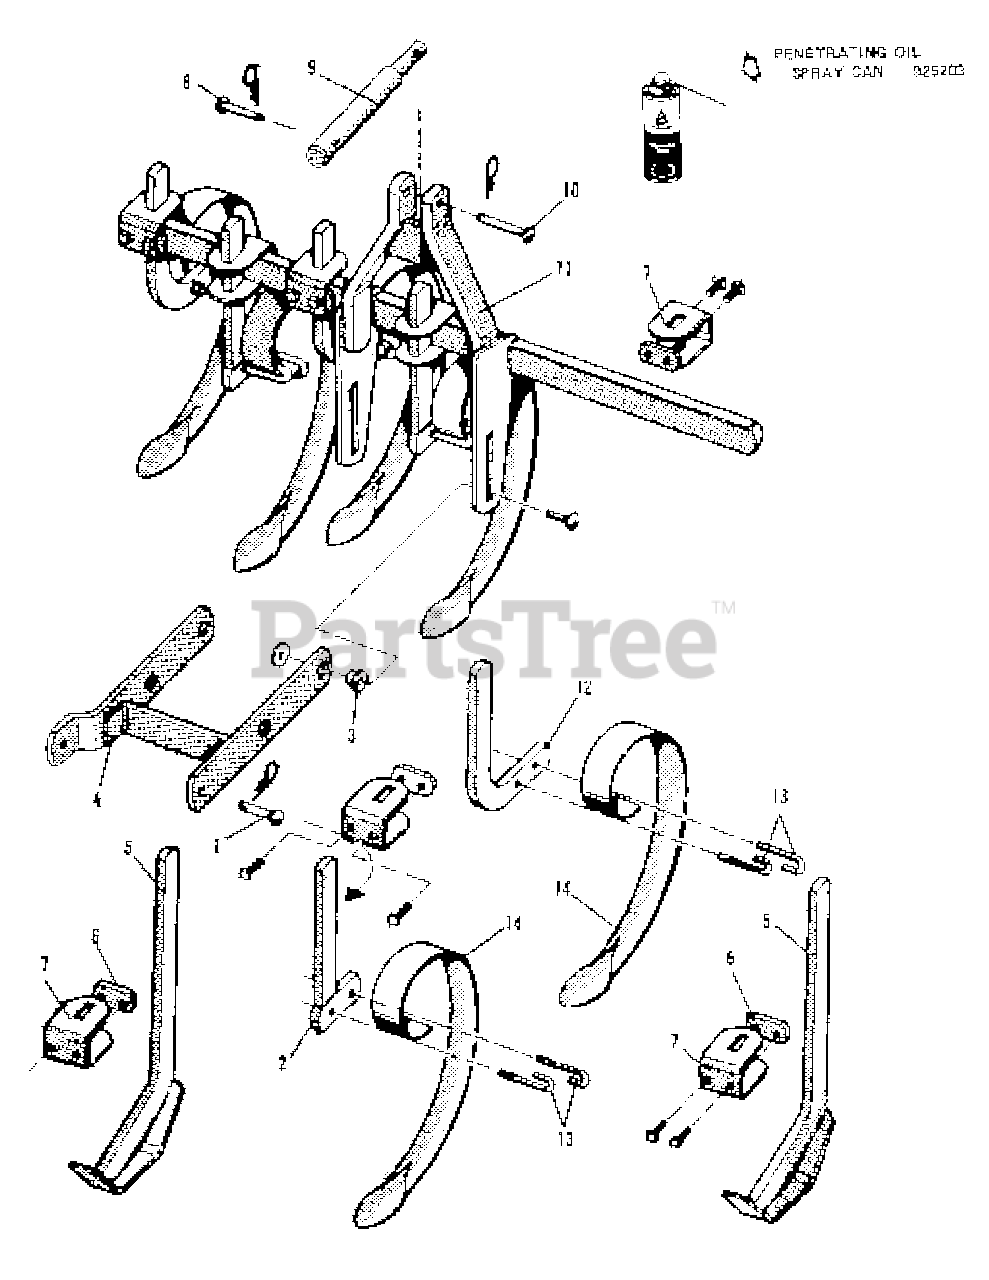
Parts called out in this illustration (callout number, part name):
1	PIN, Round Head
1	PIN, Quick
2	STANDARD ASSEMBLY, Straight
3	CARRIAGE BOLT, 7/16NC x 1-1/2
3	WASHER, 3/8
3	LOCKWASHER, 7/16
3	NUT, 7/16NC
4	ARM ASSEMBLY, Drawbar
5	SHOE ASSEMBLY, Weld
6	NUT, Special
7	CLAMP, Shank
8	PIN, Quick
9	BAR, Lift
10	PIN, Quick
11	BAR ASSEMBLY, Rear Tool
12	STANDARD, Adjusting
13	BOLT, Spring Tooth
13	LOCKWASHER, 3/8
13	NUT, 3/8NC
14	TOOTH, Spring
